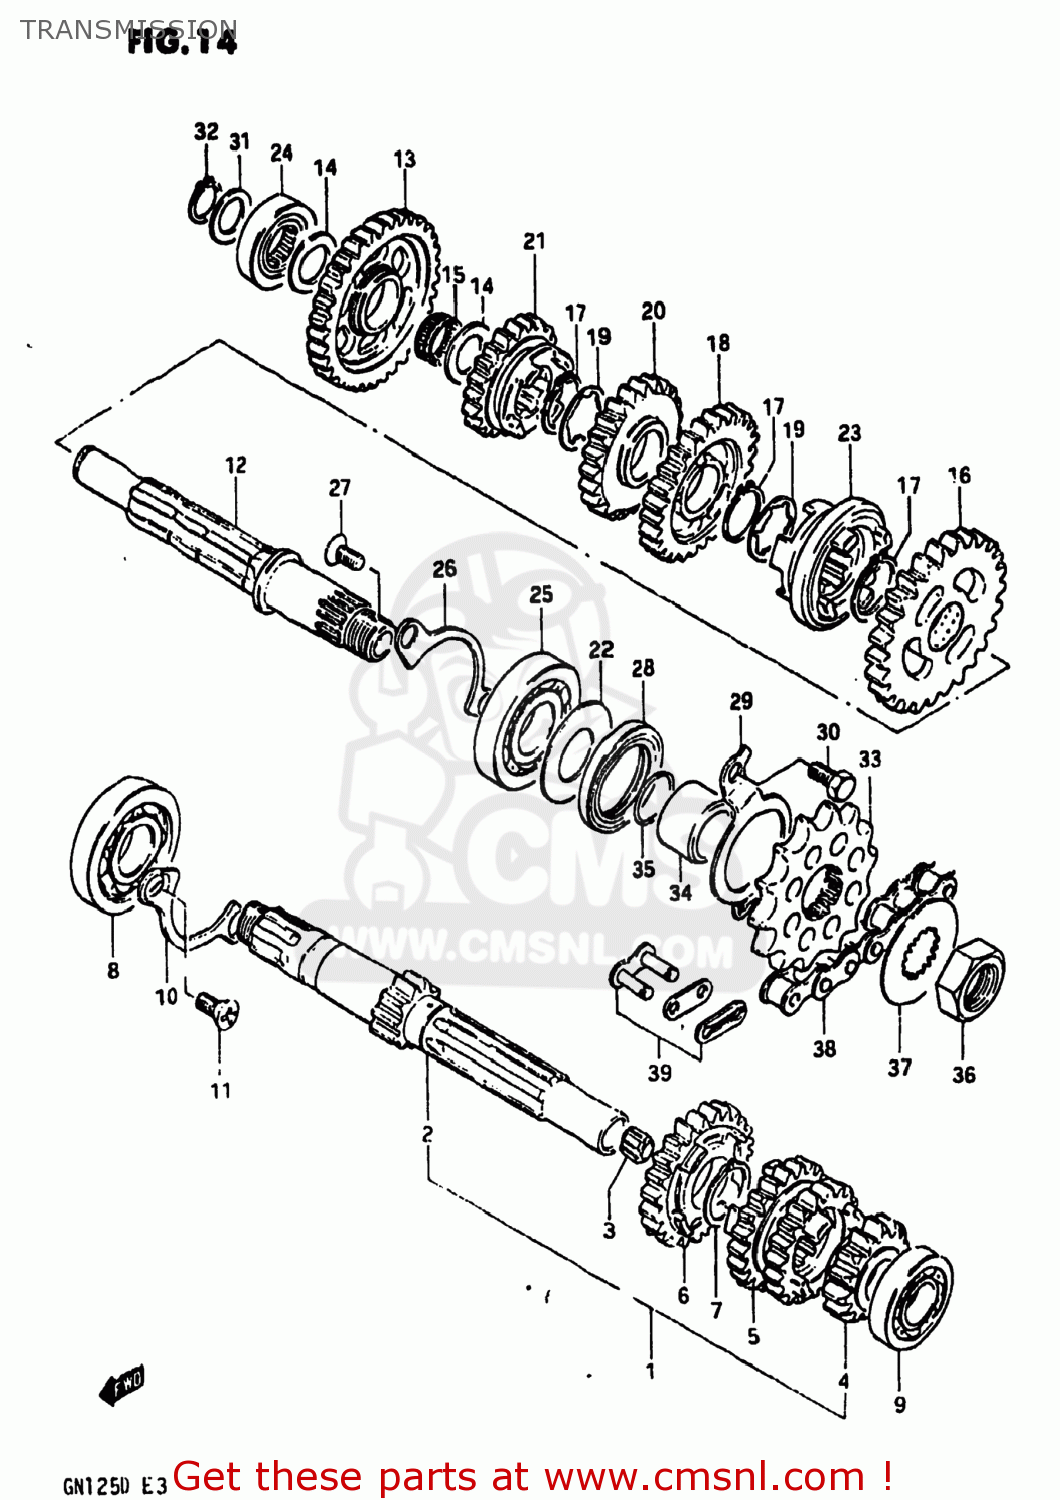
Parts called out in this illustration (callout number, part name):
1	SHAFT,COUNTER
2	SHAFT,COUNTER
3	BUSHING
4	GEAR,SECOND DRIVE
5	GEAR,THIRD & FOURTH DRIVE,N
6	GEAR,FIFTH DRIVE
7	CIRCLIP
8	BEARING
9	BEARING, LH
10	RETAINER,DRIVE SHAFT BEARING
11	SCREW
12	SHAFT,DRIVE
13	GEAR,FIRST DRIVEN
14	WASHER
15	BEARING(15X19X7.8)
16	GEAR,SECOND DRIVEN
17	CIRCLIP
18	GEAR,THIRD DRIVEN
19	WASHER,LOCK
20	GEAR,FOURTH DRIVEN
21	GEAR,FIFTH DRIVEN
22	WASHER,OIL SEALING
23	WHEEL,SLIDING DOG
24	BEARING(15X33X12)
25	Bearing
26	RETAINER,DRIVE SHAFT BEARING
27	SCREW
28	SEAL,OIL(27X40X6)
29	PLATE,DRIVESHAFT OIL
30	BOLT
31	WASHER
32	CIRCLIP,15MM
33	SPROCKET,ENGINE
34	SPACER
35	O RING(D:2.4,ID:19)
36	NUT
37	WASHER,LOCK
38	CHAIN ASSEMBLY,DRIVE
39	JOINT
